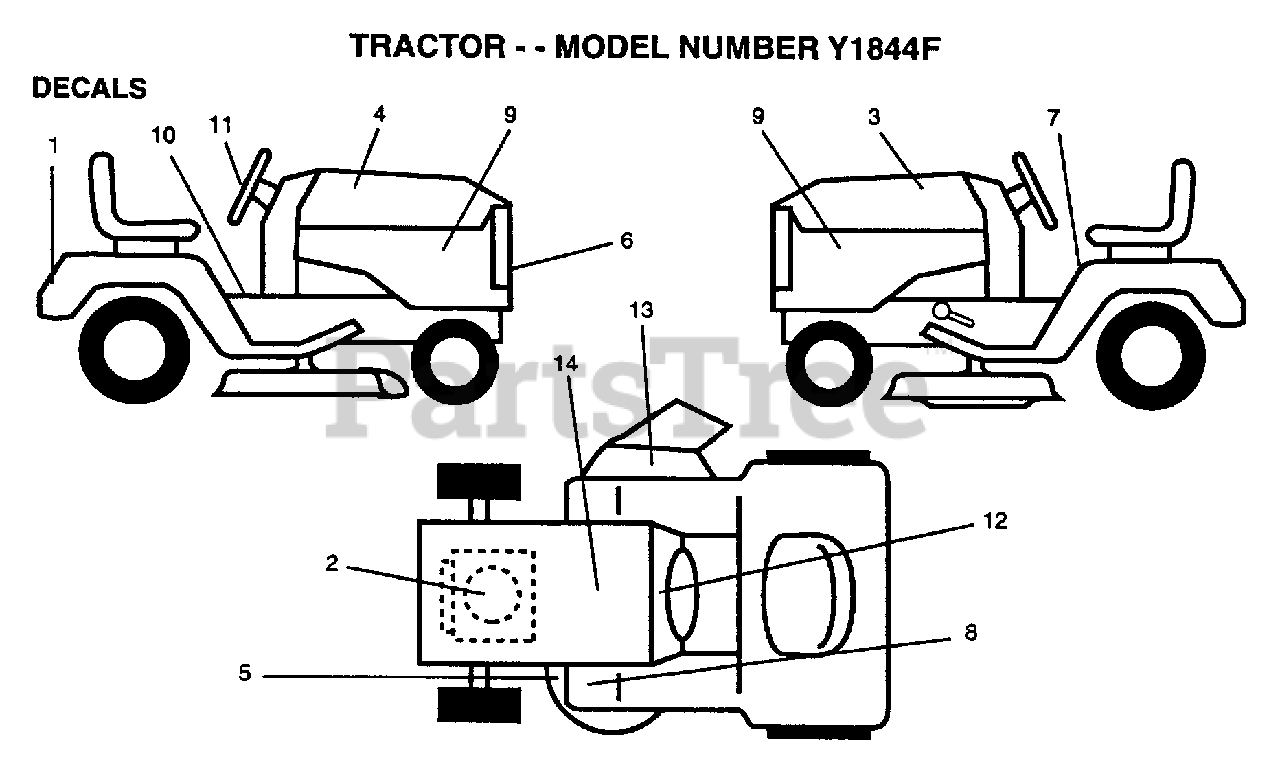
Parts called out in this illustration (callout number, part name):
2	"DECAL,HP ENGINE"
3	DECAL HOOD LH
5	"DECAL.V.BELT.44"""
6	DECAL.GRILL.YARDP
7	DECAL CAUTION
8	DECAL T
9	DECAL.PANEL.SIDE
10	DECAL BRAK PARK
11	DECAL.INS.WHL.STG
12	DECAL.DASH.INSTR.
13	"DECAL, WARNING"
14	DECAL
